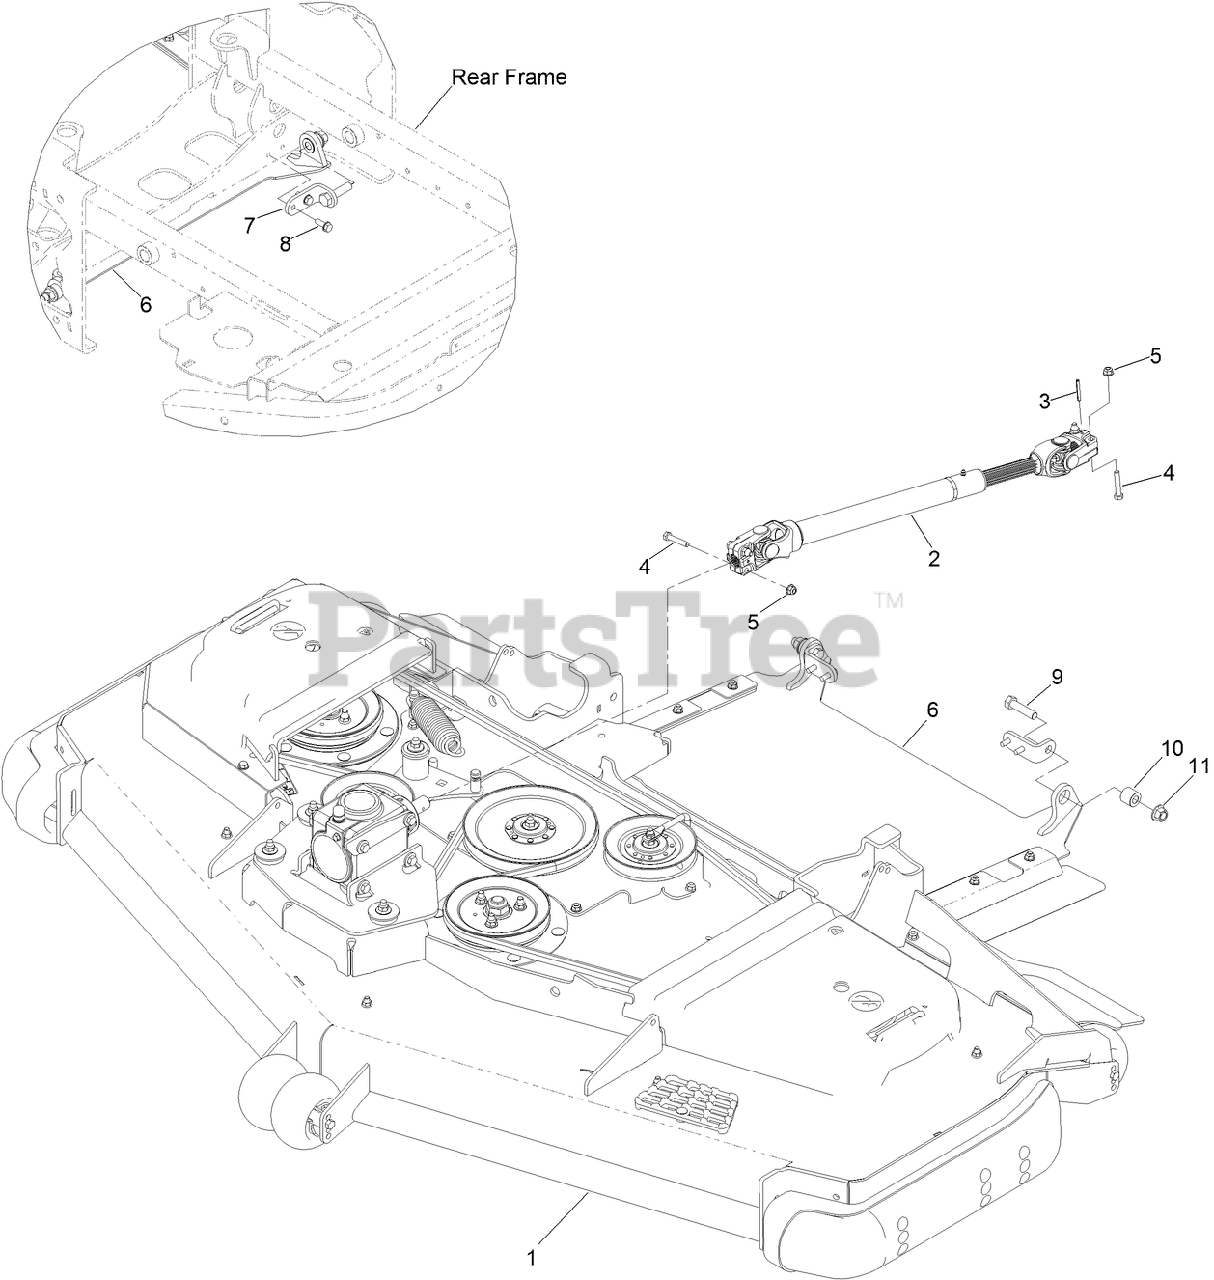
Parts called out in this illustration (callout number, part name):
2	DRIVESHAFT ASM
3	PIN-ROLL
4	SCREW-HH
5	NUT-HF, NI
6	DISCHARGE TUNNEL ASM
7	BRACKET-DISCHARGE
8	SCREW-TAPTITE
9	SCREW-HH
10	BUSHING-SLEEVE
11	NUT-LOCK
